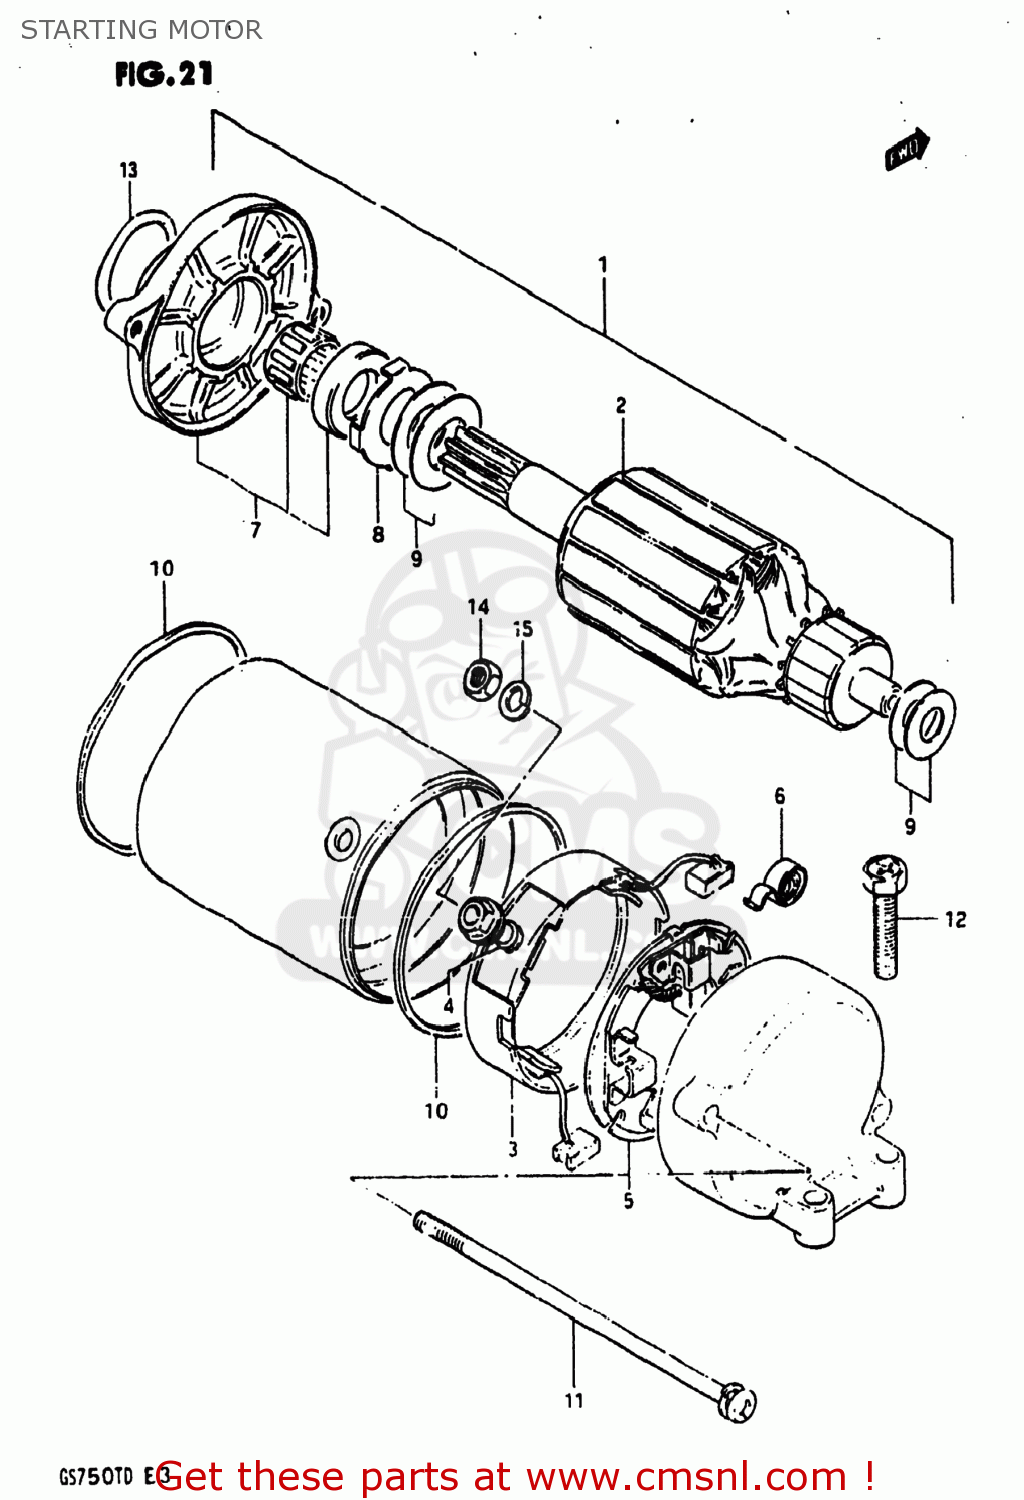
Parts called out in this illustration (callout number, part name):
1	MOTOR ASSEMBLY,STARTING
2	ARMATURE
3	BRUSH TERMINAL SET (+)
4	O RING
5	HOLDER,BRUSH
6	SPRING,BRUSH
7	HOUSING SET,STARTING MOTOR
8	SHIM SET
9	SHIM SET
10	SEAL,RING
11	BOLT,STARTING MOTOR HOUSING
12	SCREW (6X25)
13	O RING(D:2,ID:24.5)
14	NUT 6MM
15	LOCK WASHER
